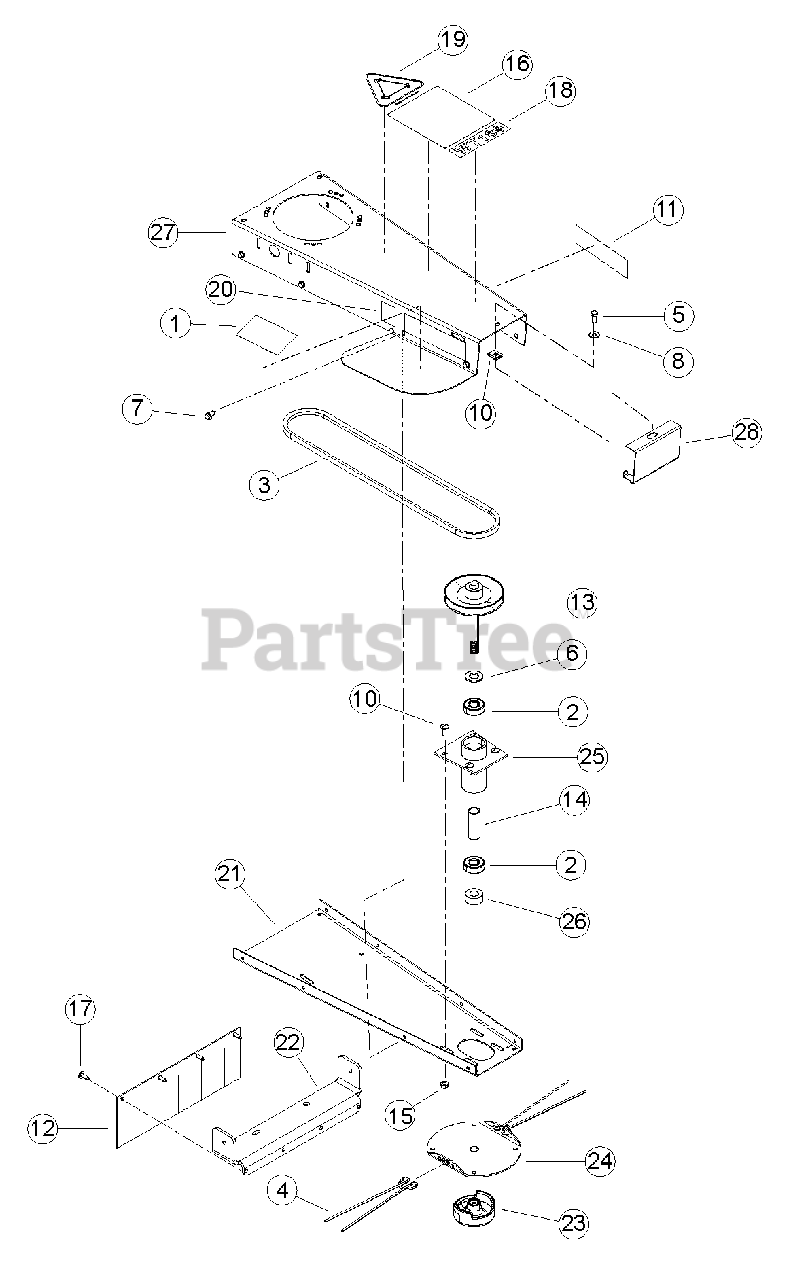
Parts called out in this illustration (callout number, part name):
1	DECAL, GRINDER DANGER
2	BEARING, 3/4 BALL
3	BELT, 4L 53 ARAMID
4	STRING, .155 X 20-1/2
5	BOLT, 5/16 X 3/4 HEX HD GR5 ZP
6	WASHER, 3/4 SAE FLAT ZP
7	SCREW, 11/32 X 7/8 HWH AB THREAD ZP
8	WASHER, 5/16 FLAT ZP
9	BOLT, 5/16 X 7/8 CRG GR5 NC ZP
10	NUT, 5/16-18 TINNERMAN U-TYPE
11	DECAL, ECHO BEARCAT 6.82 X 1.90
12	FLAP, TRIMMER
13	WELDMENT, TRIMMER PULLEY
14	SPACER, TRIMMER SPINDLE
15	NUT, 5/16-18 NYLOCK FLANGE
16	DECAL, MANUAL/SAFETY INFO
17	RIVET, PLASTIC 1/4 X 7/8
18	DECAL, MODEL WT189
19	DECAL, RECLAIM IT
20	DECAL, ECHO BEAR CAT QR CODE
21	BOTTOM, TRIMMER FRAME
22	PLATE, WT190 AXLE
23	MOWBALL, CAST TRIMMER
24	DISK, TRIMMER HEAD
25	WELDMENT, SPINDLE HUB
26	SPACER, TRIMMER HEAD
27	BODY, TRIMMER
28	COVER, FRONT TRIMMER
